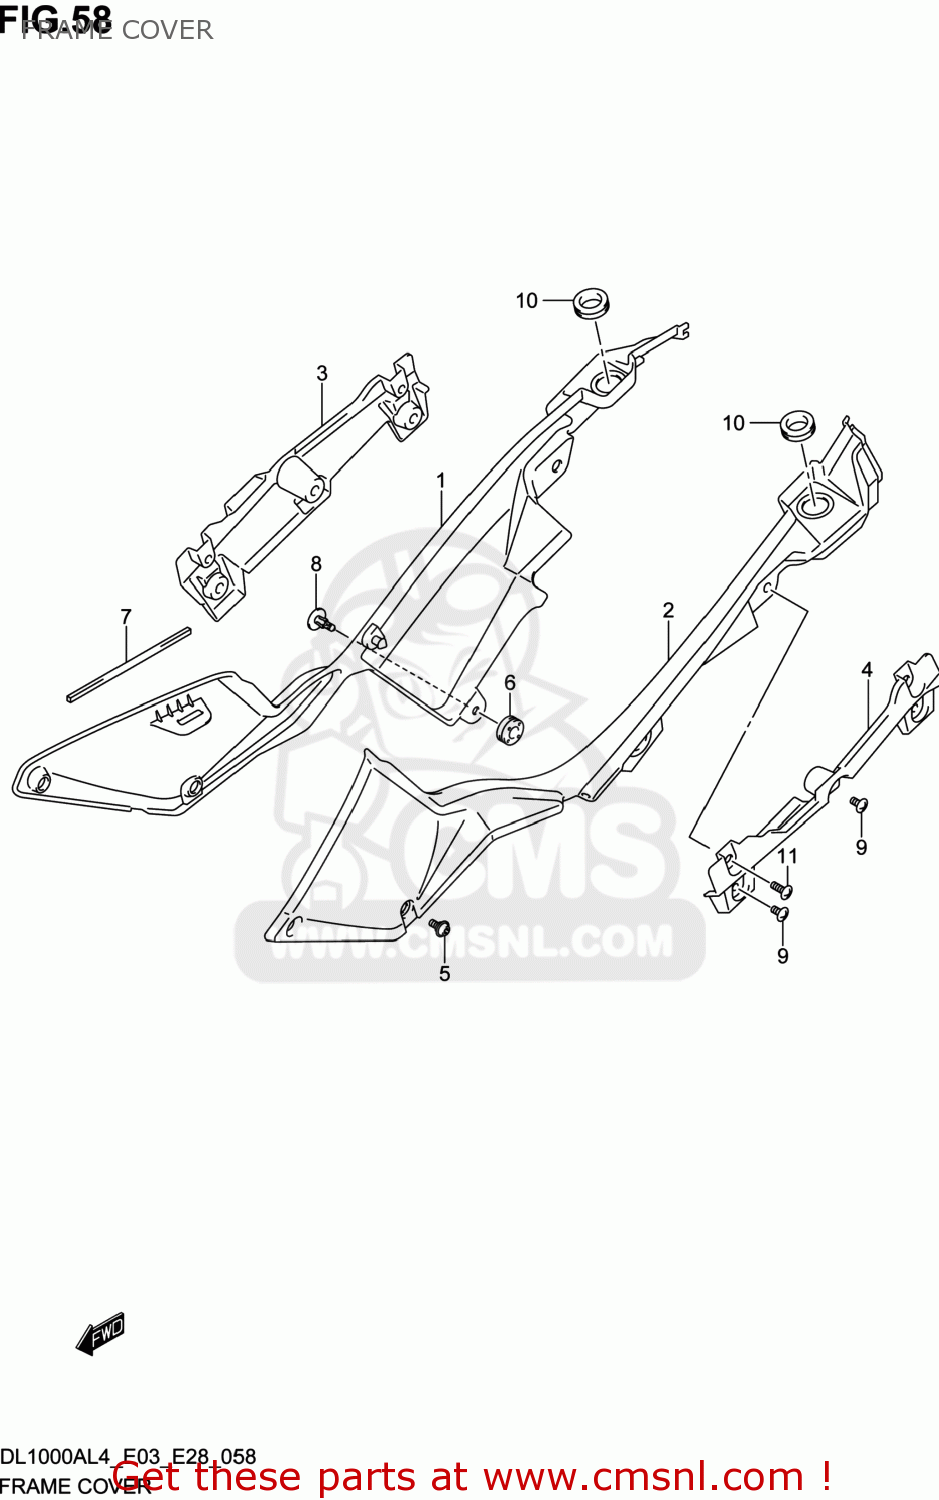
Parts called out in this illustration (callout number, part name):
1	COVER,FRAME,R
2	COVER,FRAME,L
3	COVER,FRAME REAR,R
4	COVER,FRAME REAR,L
5	BOLT(5X13)
6	CUSHION
7	CUSHION,FRAME COVER
8	CLIP
9	SCREW
10	CUSHION
11	SCREW(6X16)
